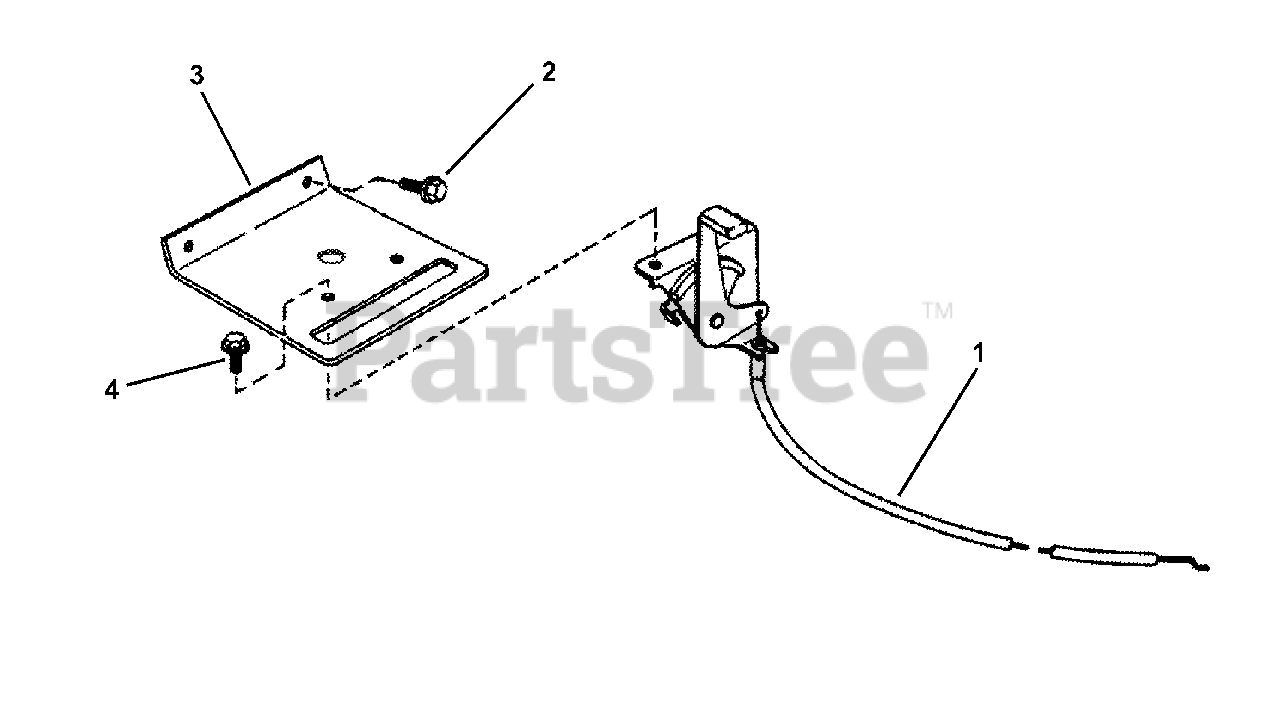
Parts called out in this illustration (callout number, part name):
1	CONTROL, Throttle (23.6" long)
2	SCREW, 1/4-20 x 1/2" Hex Washer Self-Tap
3	PLATE, Throttle Control
4	SCREW, #10-24 x 1/2" Hex Washer Self-Tap (Torx)
